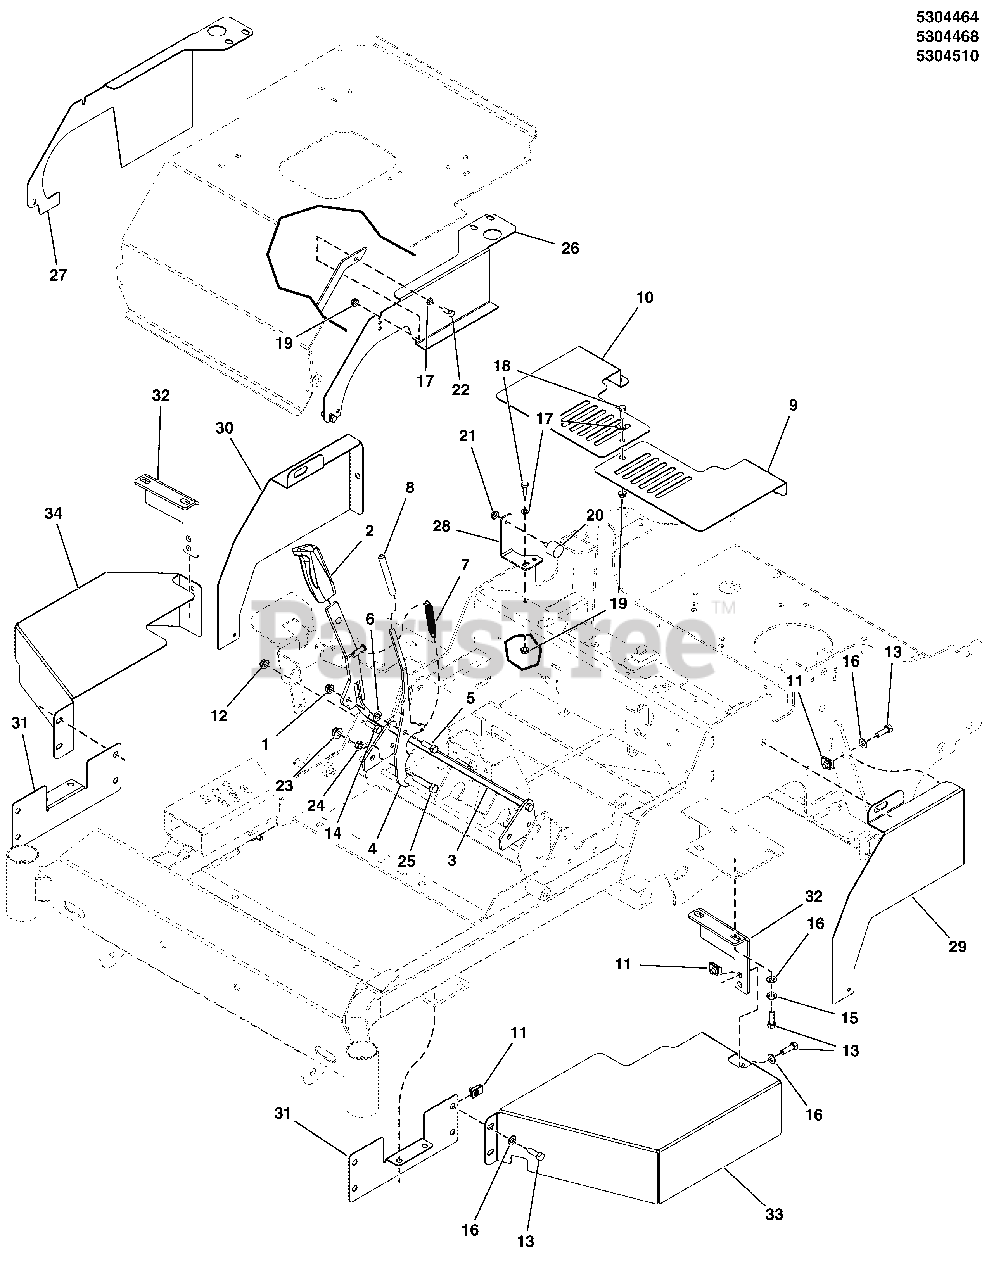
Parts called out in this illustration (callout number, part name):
1	NUT, 5/16-18 HEX NYLON LOCK
2	GRIP, BLACK FLEXIBLE
3	WELD, BRAKE SHAFT, EU - BLK
4	LEVER, BRAKE, 2500, EU - BLK
5	SCREW, TRUSS HD TORX DR5/16-18X0.875 BLK
6	WASHER,WAVE,M10
7	SPRING-EXT, .500 OD X 3.50 LG X .058 WR
8	COVER, VINYL HANDLE
9	PLATE, FAN COVER, LH - BLK
10	PLATE, FAN COVER, RH - BLK
11	BODY CLIP, 5/16-18-7GA MATERIAL
12	NUT, 5/16-18 HEX NYLOCK FLANGE
13	CAPSCREW, Hex Head, 5/16-18 x 1
14	SCREW, TRUSS HD TORX DR5/16-18X0.875 BLK
15	WASHER, 5/16 LOCK CZ
16	WASHER, 5/16 SAE
17	WASHER, Flat, 1/4
18	BOLT, 1/4-20 X 3/4 GD5 CZ
19	NUT, Nylock Flanged, 1/4-20
20	BUMPER, RUBBER 1/4-20
21	NUT, 1/4-20 HEX SERR. FLANGE
22	BOLT-1/4-20 X 5/8 GD5 CZ
23	NUT, Hex Flange, Nylock, 3/8-16
24	NUT, 3/8-16 HEX JAM
25	BOLT, 3/8-16 X 1-3/4 GD5 CZ
26	PLATE, GUARD, SEAT PLATFORM, LH - RED
27	PLATE, GUARD, SEAT PLATFORM, RH - RED
28	PLATE, BRACKET, SEAT LOCK - RED
29	PLATE, GUARD, TRANSMISSION, LH - RED
30	PLATE, GUARD, TRANSMISSION, RH - RED
31	PLATE, BRACKET, SUPPORT - RED
32	PLATE, SUPPORT, TANK - RED
33	PLATE, COVER, LH - RED
34	PLATE, COVER, RH - RED
